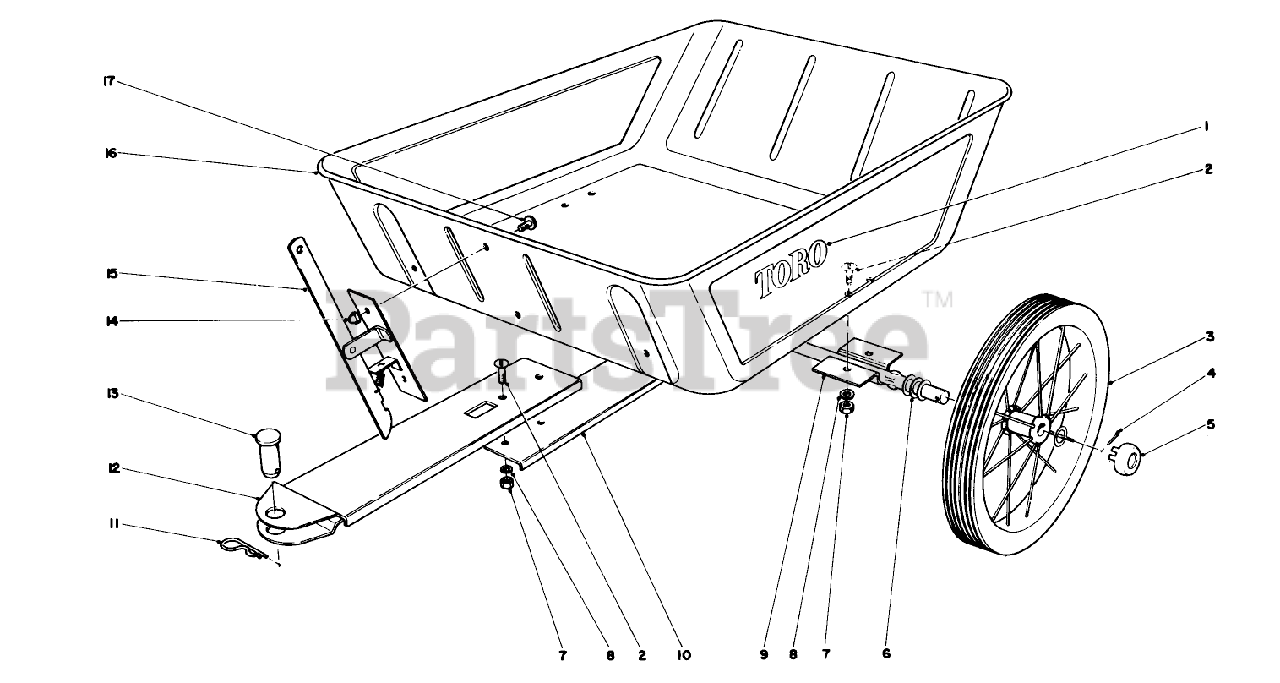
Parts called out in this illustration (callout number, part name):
1	Decal-Toro
3	Wheel 16"
4	PIN-COTTER
5	Hub cap
6	WASHER-FLAT
7	NUT-HEX
8	WASHER-LOCK
9	Axle bracket
10	Towbar
11	PIN-HAIR
12	Towbar extension
13	PIN-CLEVIS
14	Palnut
15	Trip latch
16	Hopper
17	10-24 X 3/8 TRS HD MS
